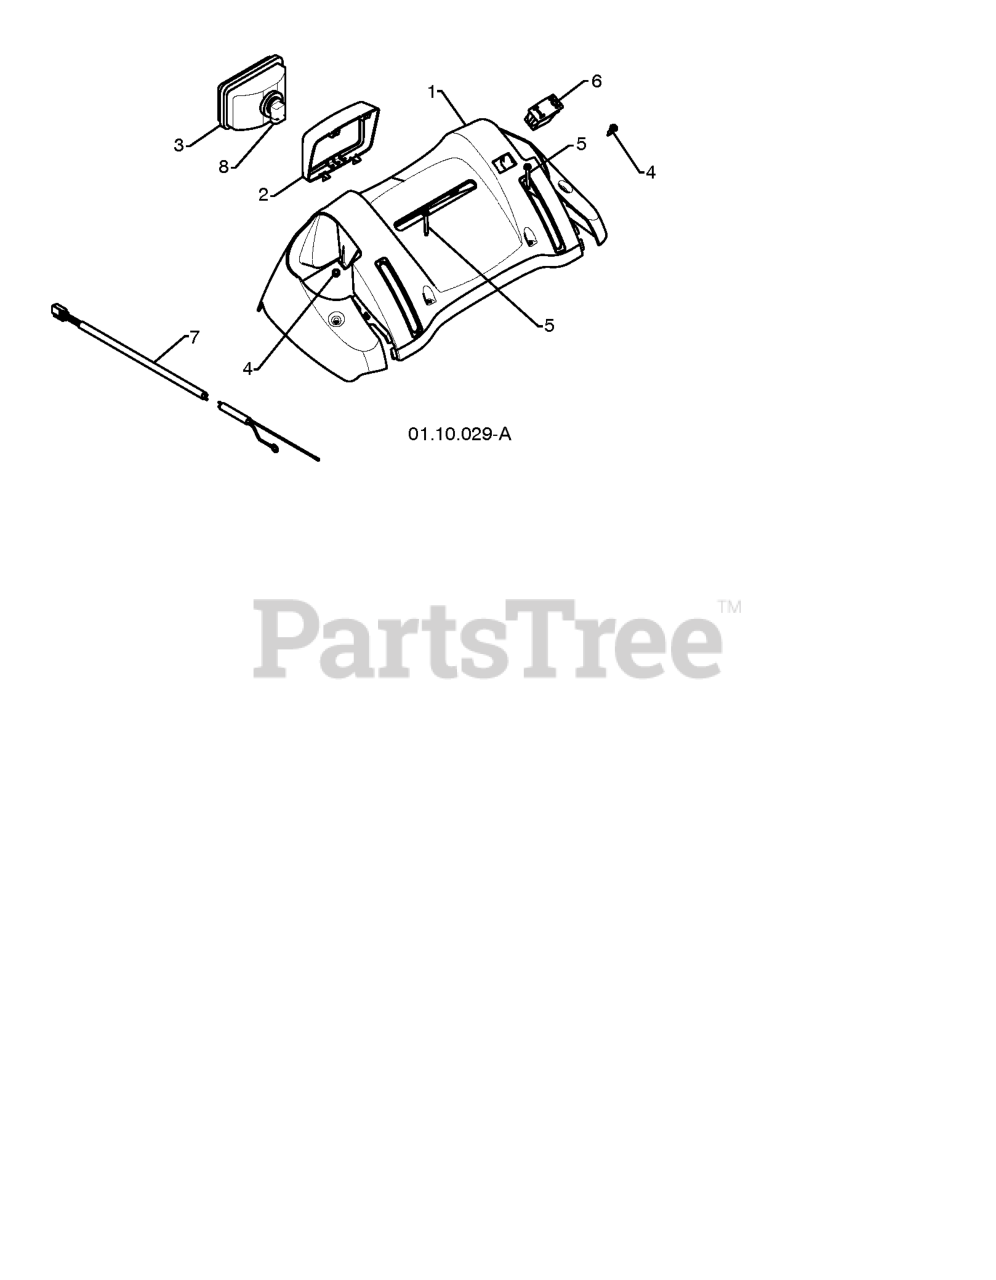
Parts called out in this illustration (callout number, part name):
1	PANEL.CONSOLE.
2	BEZEL.HEADLIGHT
3	HEADLIGHT.HALOGEN.SNOW
4	SCREW, HEX HEAD, TAPPING
5	SCREW, HEX HD TAPPING #10-24 1
6	SWITCH.HEATED.GRIP
7	HARNESS.WIRE.LIGHT/GRIP.SNOW
8	BULB.HEADLIGHT.HALOGEN.
